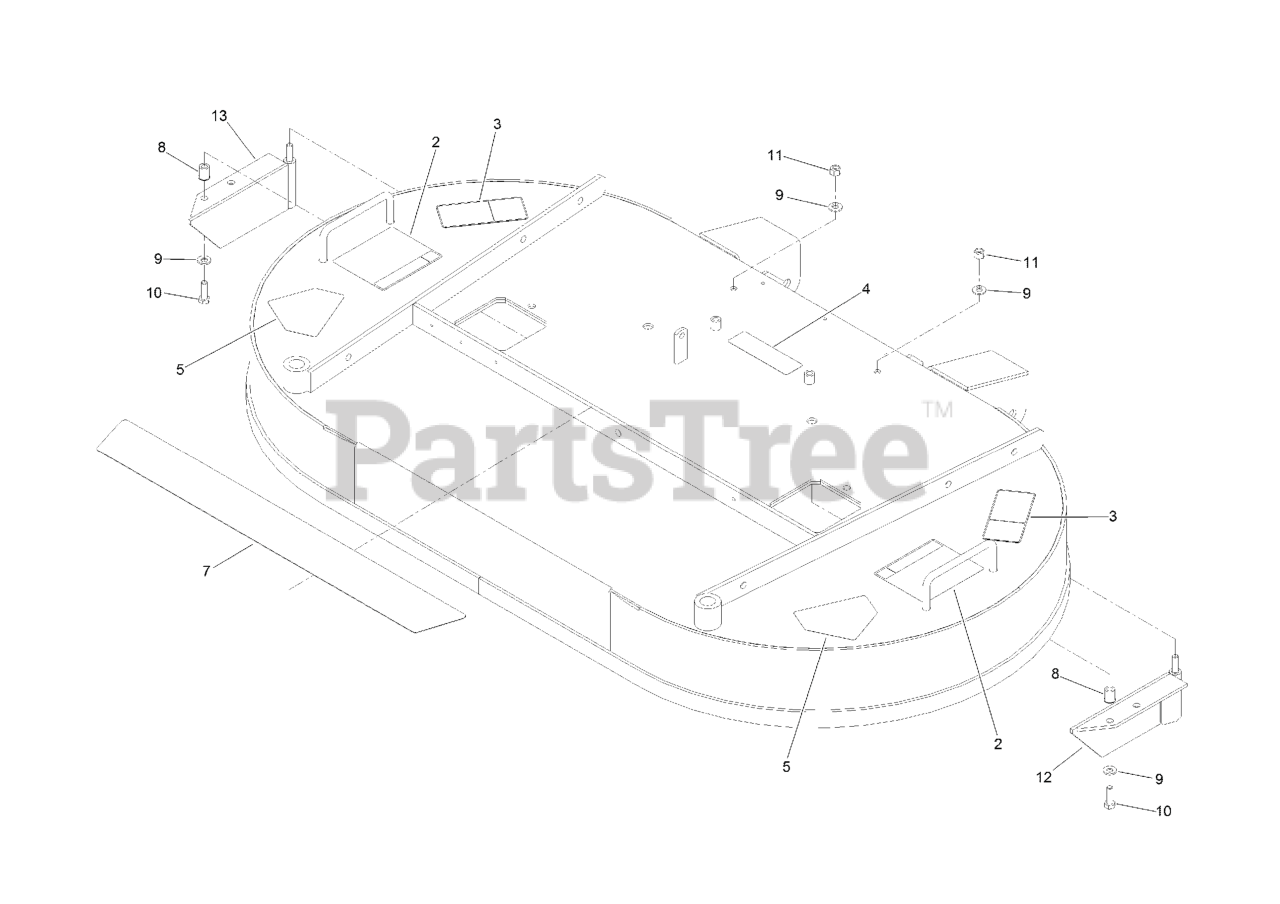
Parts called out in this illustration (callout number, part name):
2	DECAL-HEIGHT ADJUST, CUTT
3	DECAL-TORQUE, BLADE BOLT
4	DECAL-COVER, MISSING
5	DECAL-DANGER
7	PAD-ANTI SKID
8	NUT-CLINCH
9	WASHER-SPRING
10	SCREW-HH
11	NUT-LOCK, NI
12	BAFFLE-LH
13	BAFFLE-RH
